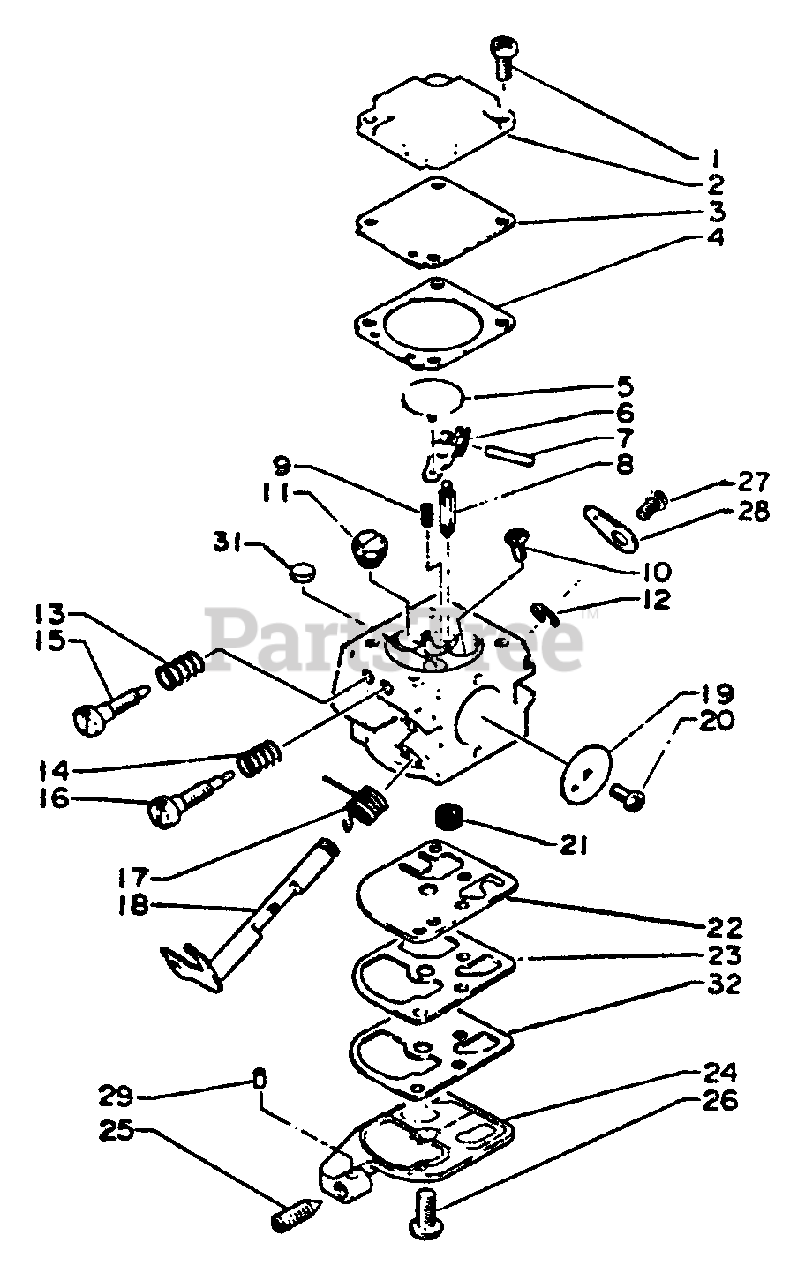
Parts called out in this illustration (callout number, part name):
1	SCREW
2	COVER, METERING
3	DIAPHRAGM
4	GASKET, METERING
5	PLUG, WELCH
6	LEVER, METERING
7	PIN, METERING LEVER
8	NEEDLE, INLET
9	SPRING, METERING LEVER
10	SCREW, METERING LEVER PIN
11	ORIFICE, MAIN FUEL
12	RING, RETAINING
14	SPRING, METERING LEVER
15	NEEDLE - HIGH SPEED
16	NEEDLE - LOW SPEED
17	SPRING, RETURN
18	SHAFT, THROTTLE
19	VALVE, THROTTLE
20	SCREW
21	STRAINER
22	DIAPHRAGM, PURGE
23	GASKET, PURGE
24	BASE, PUMP
25	SCREW, IDLE ADJUST
26	SCREW, PUMP COVER
28	LEVER, THROTTLE
29	PIECE, FRICTION
31	PLUG, WELCH
32	DIAPHRAGM, SURGE
